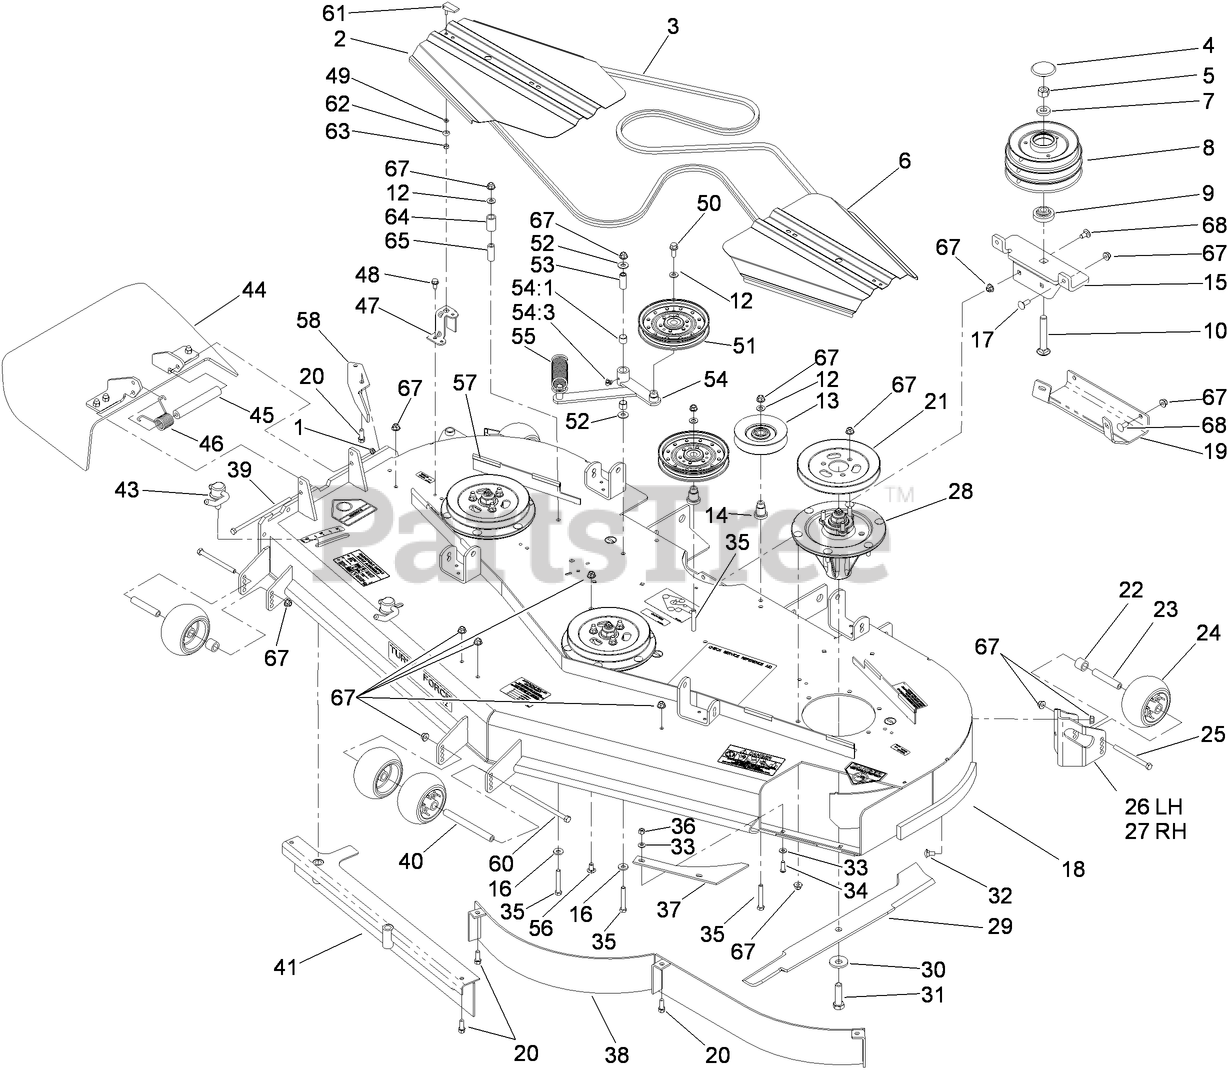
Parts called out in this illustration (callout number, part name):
1	NUT-LOCK, NI
2	COVER-BELT, LH
3	BELT-V
4	CAP-PLASTIC
5	NUT-HEX
6	COVER-BELT, RH
7	SPACER
8	PULLEY AND BEARING ASM
9	SPACER-FLANGED
10	BOLT-CARRIAGE
12	WASHER-FLAT
13	PULLEY-IDLER
14	MOUNT-PULLEY
15	MOUNTING BRACKET ASM
16	WASHER-BELLEVILLE
17	BOLT-CARR
18	DECK DECAL ASM
19	Plate-Skid
20	SCREW-HWH
21	PULLEY
22	TUBE-SPACER
23	TUBE-SPANNER
24	ROLLER-SCALP, ANTI
25	SCREW-HH
26	MOUNT-WHEEL, LH
27	MOUNT-WHEEL, RH
28	SPINDLE ASM
29	BLADE-HI FLOW, 24.5 INCH
30	Washer-Blade Bolt, Heavy
31	SCREW-BLADE
32	SCREW-CARR
33	WASHER-SPRING
34	SCREW-HSBH
35	SCREW-HH
36	NUT-LOCK, NI
37	PLATE-TURBO
39	SCREW-HH
40	SPACER-WHEEL
43	LEVER ASM
44	RUBBER DEFLECTOR ASM
45	SPACER
46	SPRING-TORSION
47	BRACKET-COVER
48	SCREW-HWHTF
49	WASHER
50	SCREW-HHF
51	Idler-Flat
52	WASHER-FLAT
53	BUSHING
54	IDLER ARM ASM
54:1	SLEEVE-BEARING
54:3	FITTING-GREASE, 90 DEG
55	SPRING-EXTENSION
56	SCREW-CARR
57	STRIP-SEAL
58	BAFFLE-DISCHARGE
60	SCREW-HH
61	HANDLE-LATCH, SWELL
62	BUSHING-LATCH, SWELL
63	NUT-LOCK, HH
64	SPACER-RUBBER
65	SPACER-PIVOT, IDLER
67	NUT-HF, NI
68	SCREW-CARR
